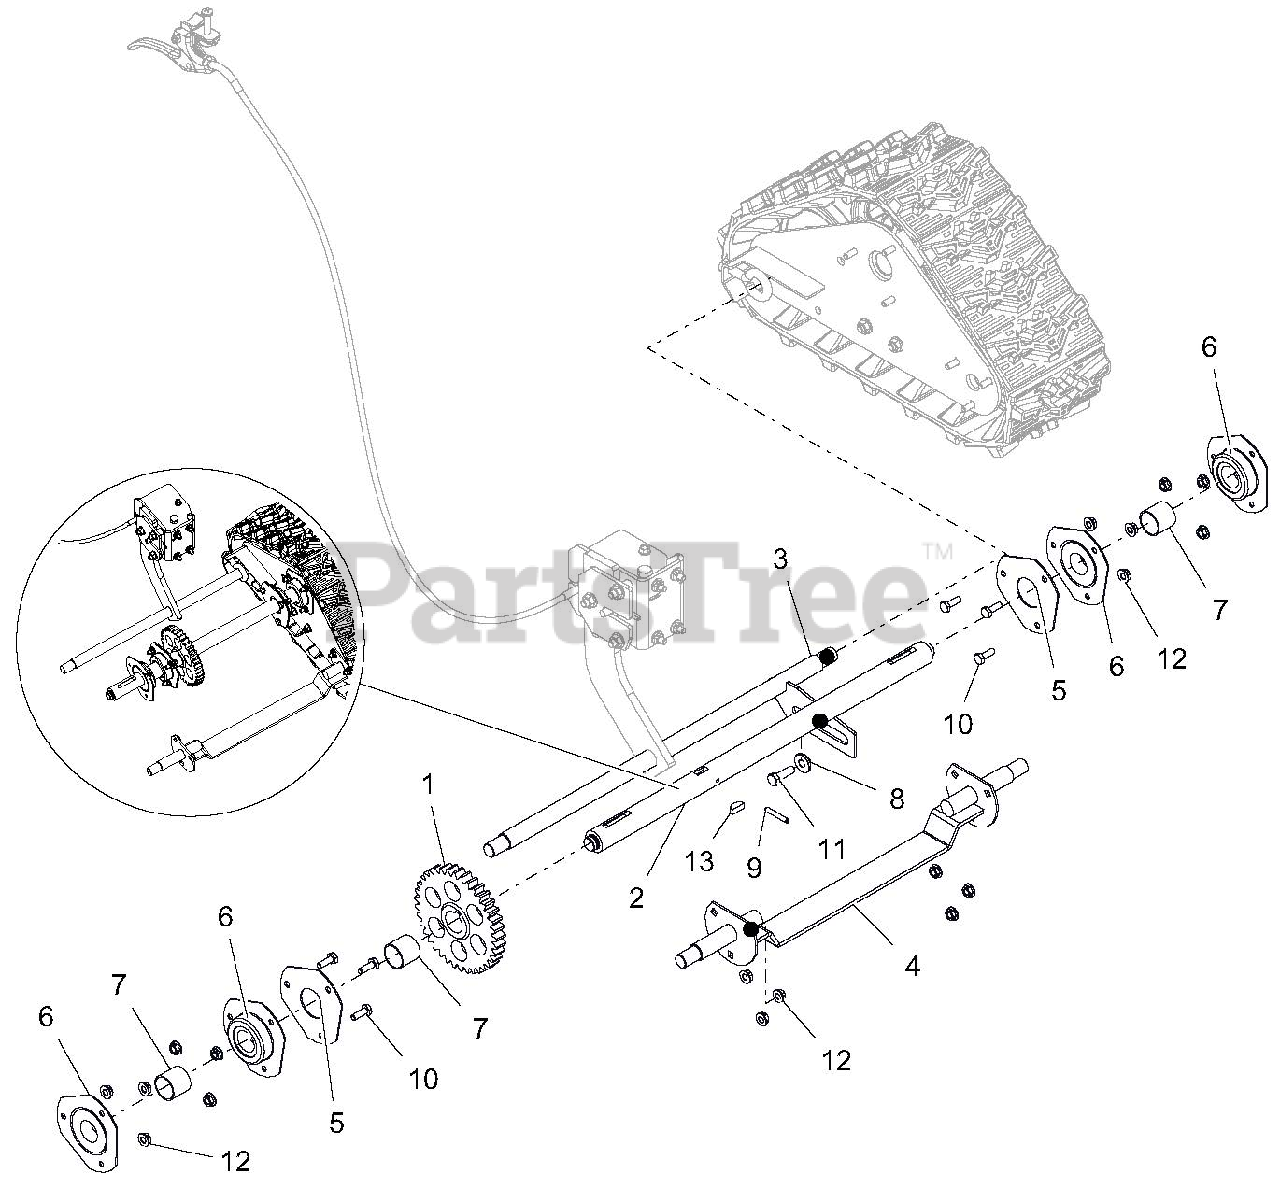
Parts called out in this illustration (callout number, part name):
1	GEAR, SPUR
2	AXLE, TRACK-DELUXE
3	AXLE, REAR - DELUXE TRACK
4	AXLE, FRONT-COMPACT TRACK
5	PLATE, BEARING SPACER
6	BRG-FLG 1.003/1.000 3 BOLT
7	BSHG-SLV, 1.012X1.125X1.00
8	BSHG-FLG .325X.499X.3X.875
9	PIN-ROLL .188X1.25
10	@BLT-HEX .25-20X.75 GR5 YWZC
11	@BLT-HEX .31-18X1.00 GR5 YWZC
12	@NUT-LK-CTR-FLG .25-20 YWZC
13	KEY-WDRF .25X.750X.313 SAE91
